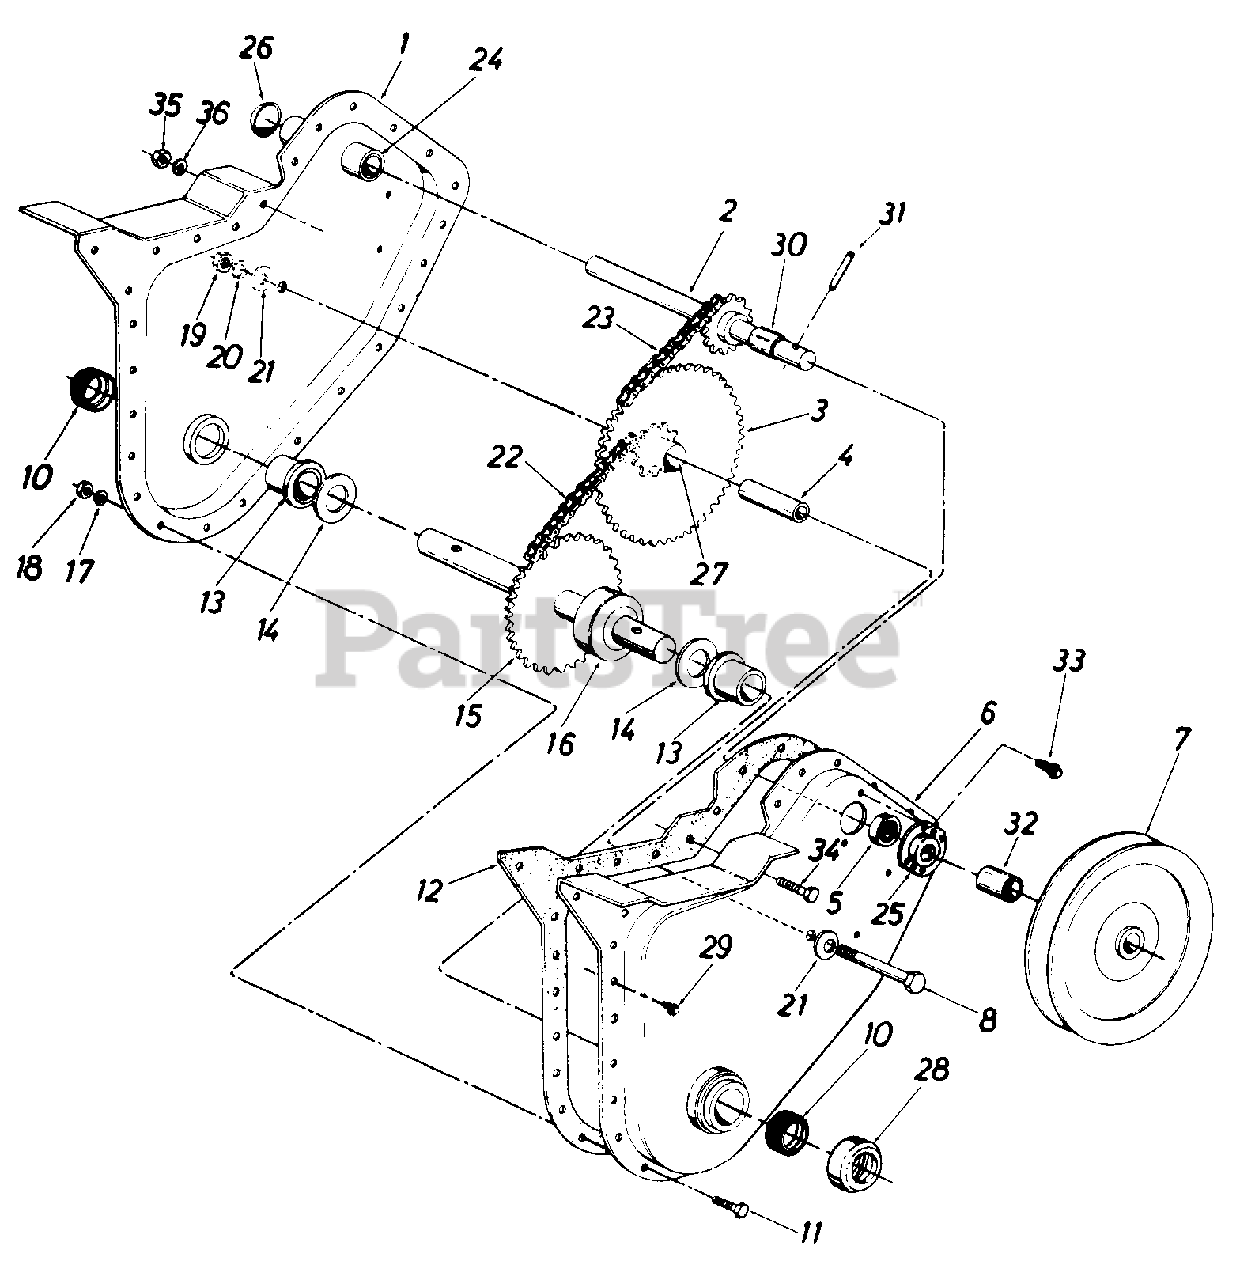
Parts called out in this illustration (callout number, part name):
1	Chain Case Ass'y.-R.H.
2	Input Shaft Ass'y.
3	Hub and Sprocket Ass'y.
4	Bearing Inner Race
5	Ball Bearing
6	Chain Case Ass'y.-L.H.
7	Pulley-Chain Case
8	Hex Bolt 3/8-24 x 2.5" Lg.
11	Hex Bolt 1/4-28 x .625" Lg.
12	Gasket
13	Flange Brg. .879" I.D.
14	Fl-Wash. .88" I.D. x 1.5"
15	Tine Shaft Ass'y.
16	Spacer 7/8" I.D. x 2" O.D. x.68" Lg.
17	L-Wash. 1/4" I.D.
18	Hex Nut 1/4-28 Thd.
19	Hex Ins. L-Nut 3/8-24 Thd.
20	L-Wash. 3/8" I.D.
21	Bell-Wash. .406" I.D.
22	Chain #420 1/2" Pitch x 37 Links
23	Chain #35 .375" Pitch x 49 Links
24	Bearing .62" I.D. x .813
25	Bearing Housing
26	Expansion Plug 13/16" Dia.
27	Bearing
29	Hex Wash. Hd. Self-Tap Scr. 1/4-20 x .50" Lg.
30	Spacer .63" I.D. x .77" O.D. x .38" Lg.
31	Spring Pin Spiral 1/4" Dia. x 11/2" Lg.
32	Spacer .647 x 1.25"
33	Hex Wash. Hd. Self-Tap Scr. l/4-20 x .38" Lg
34	Hex Bolt 5/16-18 x .75" Lg.
35	Hex Nut 5/16-18 Thd.
36	L-Wash. 5/16" I.D.
